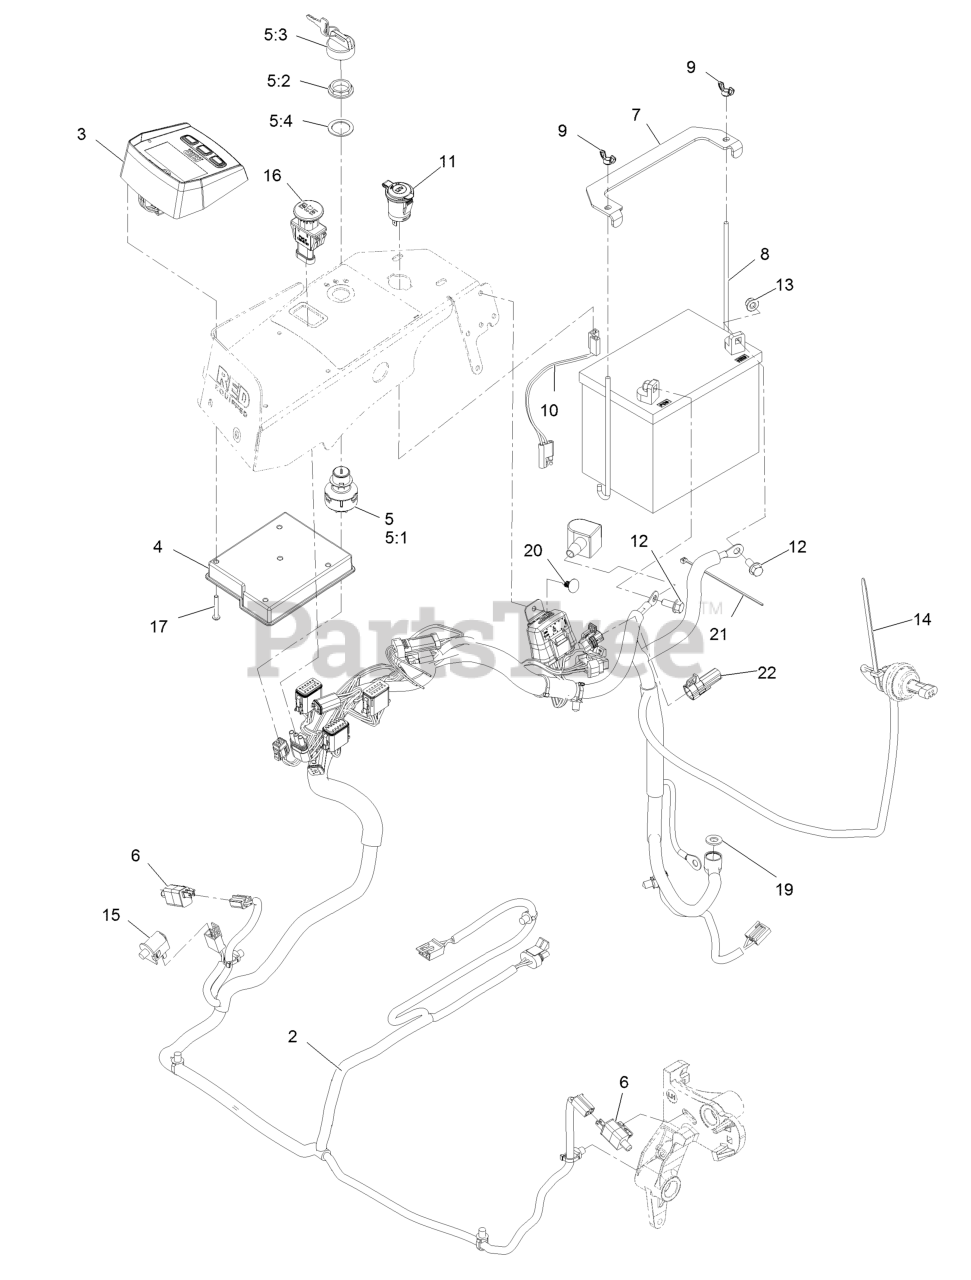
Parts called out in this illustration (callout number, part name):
2	Harness-Wire
3	Module, Ldu
4	Module-Mcu
5	Ignition Switch ASM
5:1	Switch-Ignition
5:2	Nut-Mounting
5:3	Ignition Key Set
5:4	Washer-Backup
7	Strap-Tie Down, Battery
8	Bolt-Holddown
9	Wingnut-Nyloc 1/4-20
10	Harness-Receptacle, 12V
11	Port-Power, 12V
12	Screw-HH Flg 5/16-18 X 3/4
13	Nut-Nyloc 5/16-18 Flg
14	Tie-Cable 7 15/16 (Large)
16	Switch-PTO, Sealed
17	Screw-PPH
19	Washer-3/8 SAE
20	Plug-Plastic
21	Tie-Cable 5 1/2 (Small)
22	Cover-Connector, Mp150, 4M
